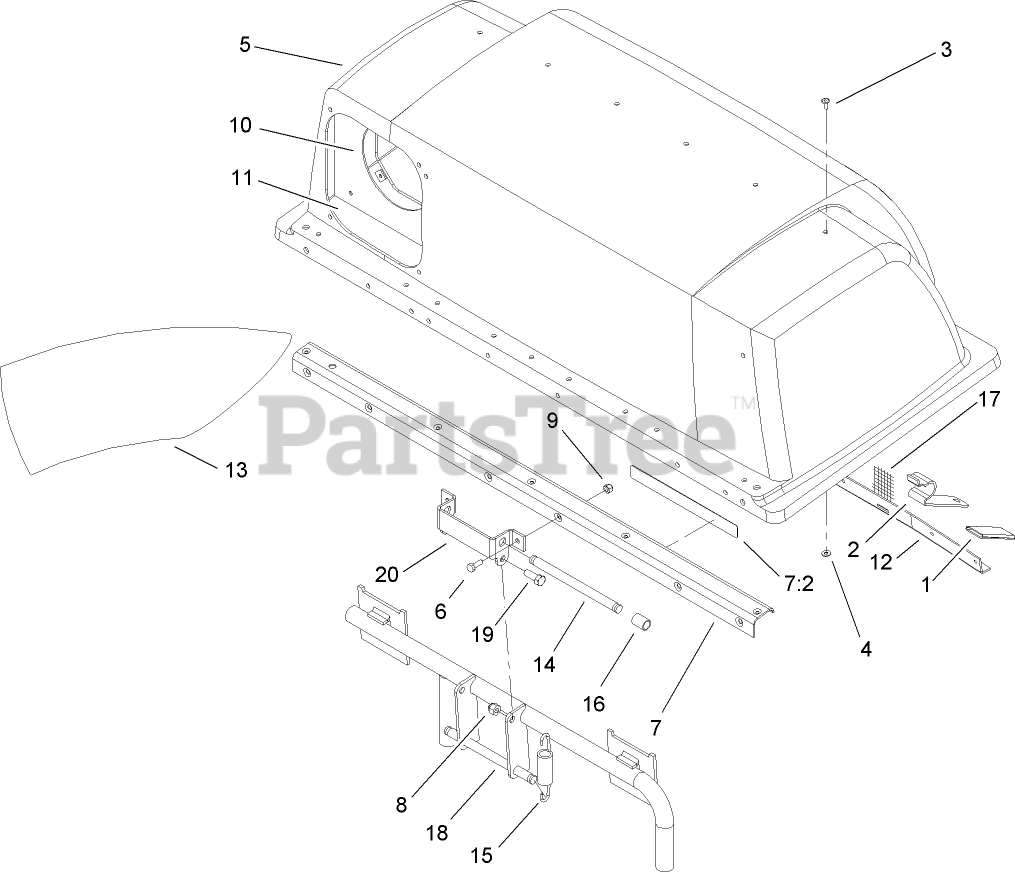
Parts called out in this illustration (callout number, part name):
2	LATCH-BAGGER, TOP
3	RIVET-BLIND
4	WASHER-FLAT
5	TOP-BAGGER
6	SCREW-HH
7	STIFFENER ASM
7:2	DECAL-CAUTION
8	NUT-LOCK, NI
9	NUT-LOCK, NI
10	CLAMP-SEAL
11	SEAL-CHUTE
12	SUPPORT-SCREEN
13	CHUTE-BAGGER
14	PIN-SPRING
15	SPRING-EXTENSION
16	SPACER
17	SCREEN-BAGGER
18	FRAME ASM
19	SCREW-HH
20	HINGE-BAG, TOP
